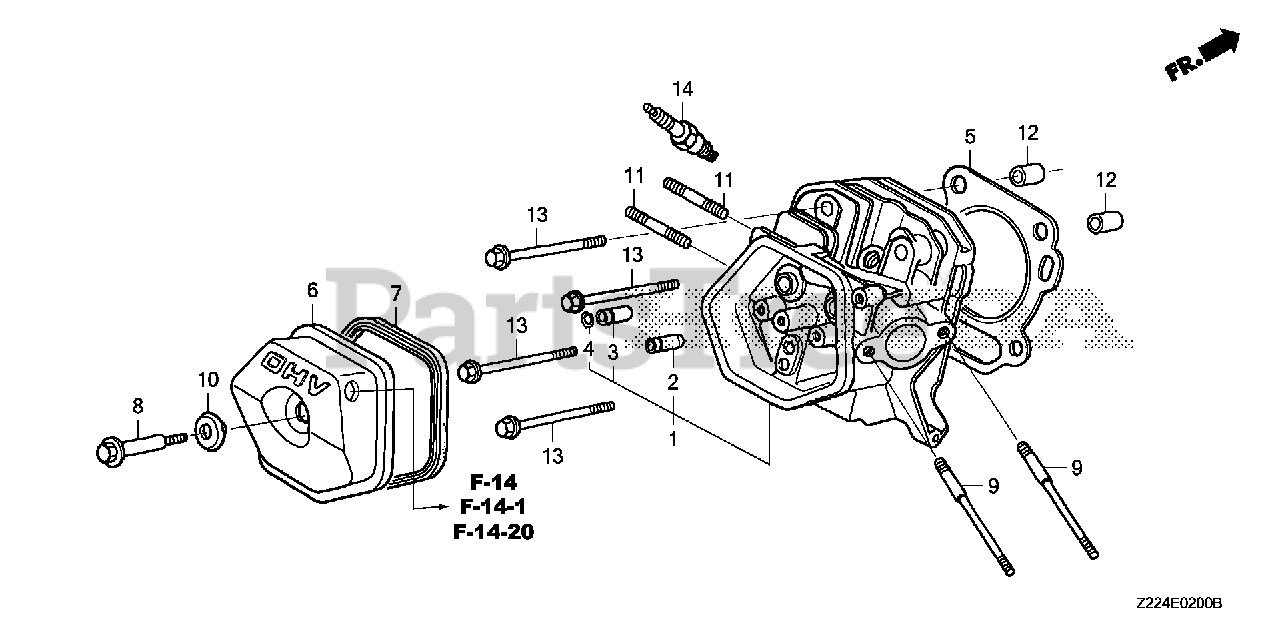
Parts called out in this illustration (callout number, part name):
1	CYLINDER HEAD
2	GUIDE, VALVE (OVER SIZE)
3	GUIDE, EX. VALVE (OVER SIZE)
4	CLIP, VALVE GUIDE
5	GASKET, CYLINDER HEAD
6	COVER, HEAD
7	GASKET, HEAD COVER
8	BOLT, HEAD COVER
9	BOLT, STUD (8X115)
10	WASHER, HEAD COVER
11	BOLT, STUD (8X32)
12	PIN, DOWEL (12X20)
13	BOLT, FLANGE (10X80)
14	SPARK PLUG (BPR5ES) (NGK)
14	SPARK PLUG (W16EPR-U) (DENSO)
